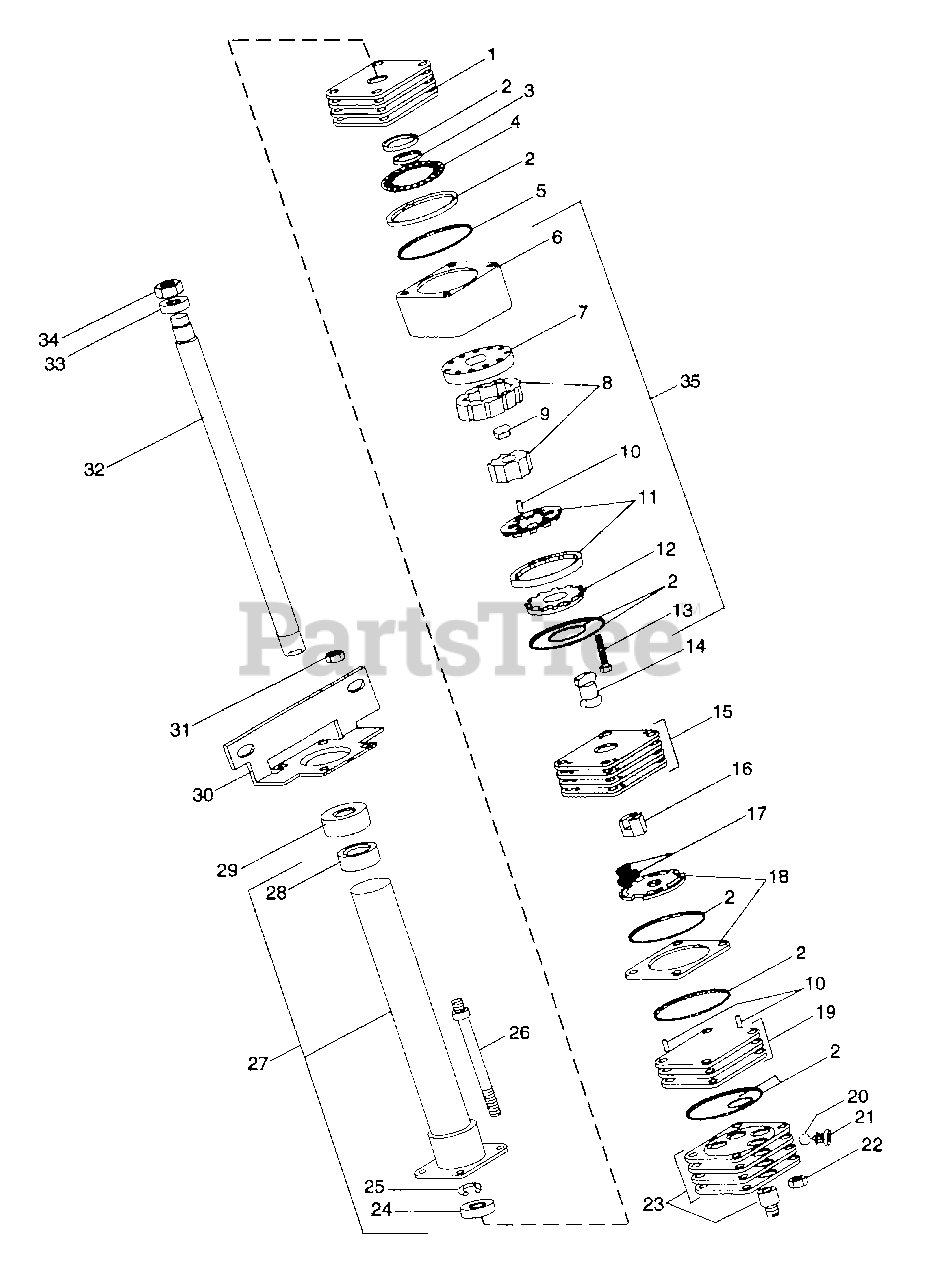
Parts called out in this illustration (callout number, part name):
1	UPPER COVER PLATE
2	SEAL SERVICE ASS'Y
3	SEAL SPACER
4	THRUST BEARING
5	SPACER-ROSS SERVICE
6	METERING RING
7	DRIVE PLATE
9	SPACER-ROSS SERVICE
10	NEEDLE ROLLER SERVICE ASS'Y
11	COMMUTATOR & RING ASS'Y
12	COMMUTATOR COVER
13	SCR-SPECIAL ROSS
14	DRIVE LINK
15	ISOLATION MANIFOLD
16	HEX DRIVE
17	SPRING SERVICE ASS'Y
18	VALVE & RING ASS'Y
19	PORT MANIFOLD
20	BALL - STEEL
21	PLUG & O-RING ASS'Y
22	NUT-LK-CTR .312-24 PL
23	PORT COVER
25	RG-RTNG ROSS #401465
26	STUD-SPECIAL SV ROSS
27	UPPER COVER & JACKET TUBE ASS'
28	COLUMN BEARING SET
30	BRACKET
31	NUT-LK TOP .312-24 PL GR C
32	INPUT SHAFT SERVICE ASS'Y
33	DUST COVER
34	NUT-LK-JAM .625-18 YWZC
35	METERING ASS'Y
